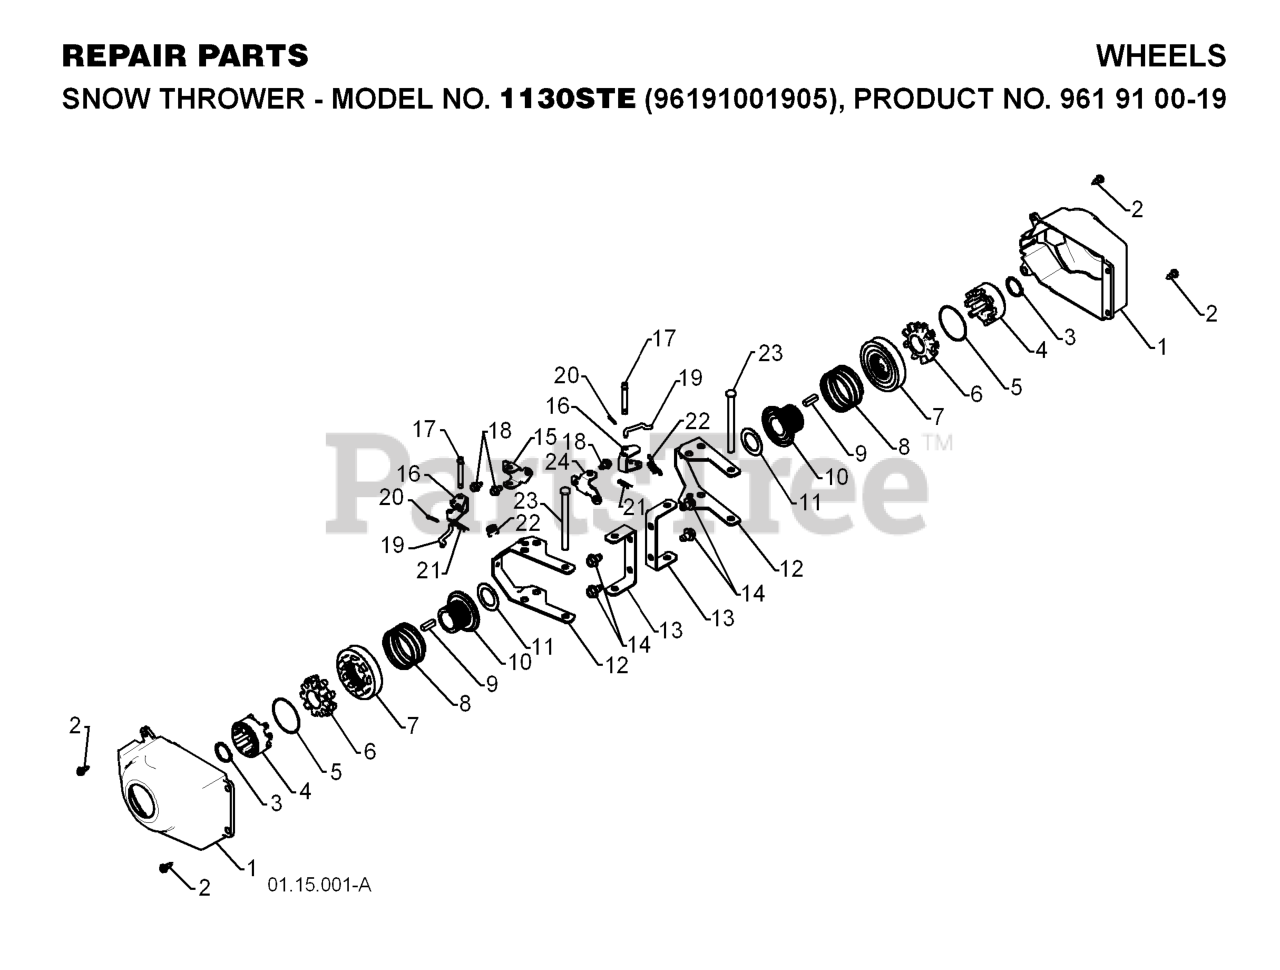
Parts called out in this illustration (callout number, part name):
1	COVER, POWER STEERING
2	SCREW, HEX HEAD, TAPPING
4	RP.DRIVER WHEEL
5	RING, WIRE RETAINER
6	LOBE WHEEL
7	RP.SLIDE.CLUTCH
8	SPRING, CLUTCH SLIDE
9	KEY, SQUARE 1/4 X .875
10	RP.LOBE.AXLE
11	WASHER TRUST 1"
12	YOKE, STEERING
13	BRACKET.STEER.PNT.BLACK
14	Screw 5/16-18 x 1/2 Hex, Self Tapping 5/16-18 x 1/2
15	BRKT.STEER.PIVOT.RH
16	BELLCRANK.STEER
17	PIN, STEERING BELLCRANK
18	SCREW 1/4X20
19	LINK.STEER.YOKE
20	RETAINER CLIP
21	RETAINER CLIP PM
22	SPRING LATCH
23	PIN, STEERING LEVER
24	BRACKET.STEER.PIVOT.LH.YZ
